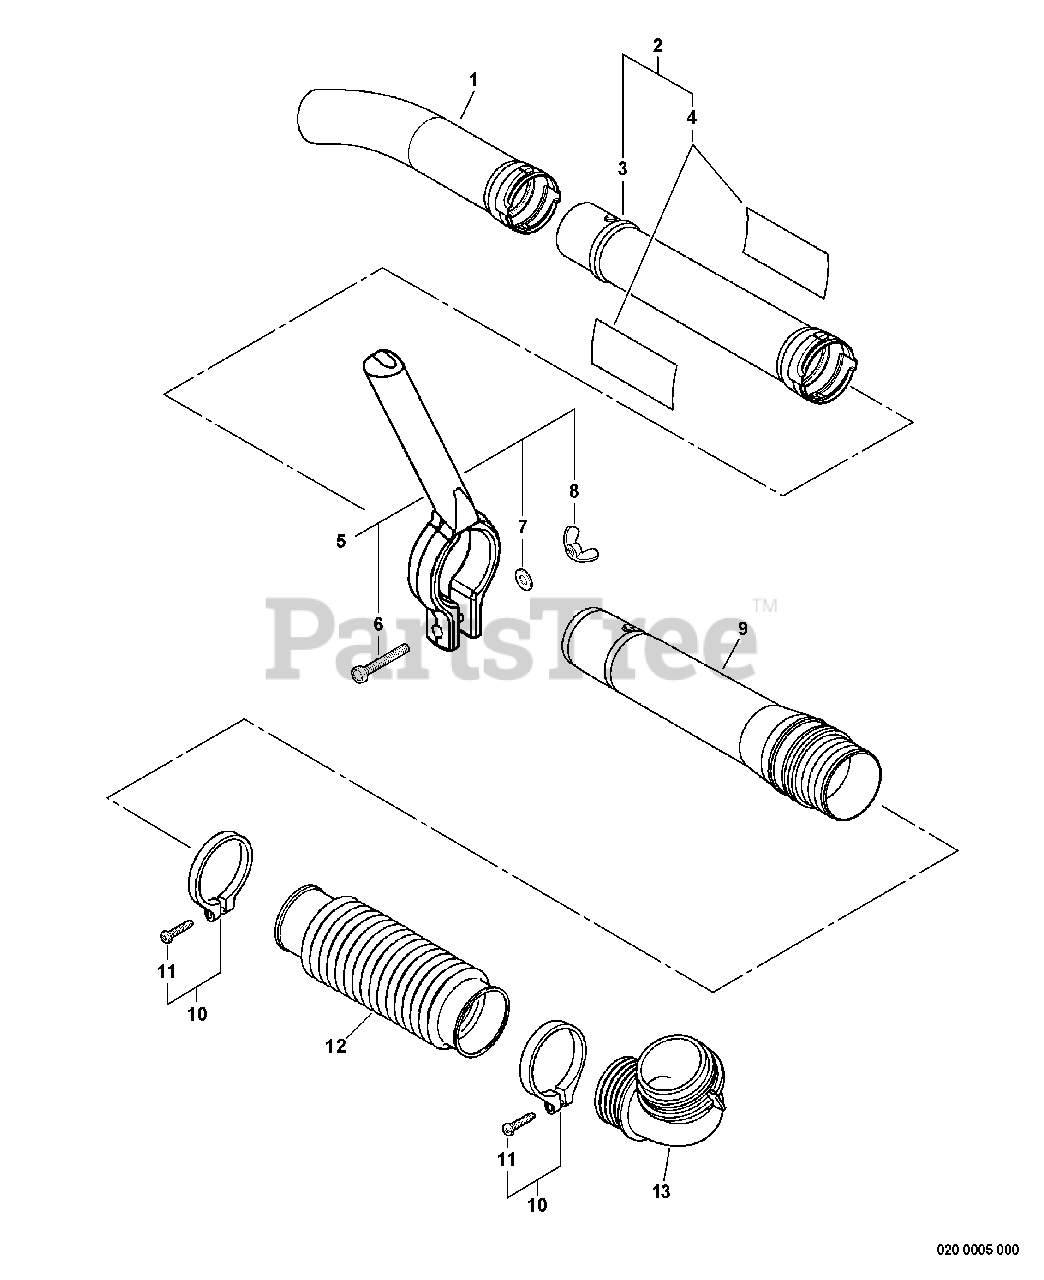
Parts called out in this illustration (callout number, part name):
1	TUBE, BLOWER - CURVED
2	BLOWER TUBE KIT - STRAIGHT
3	TUBE, BLOWER - STRAIGHT
4	LABEL - ECHO
5	HANDLE ASSY
6	BOLT 6×45
7	WASHER 6.5×11.5×0.8
8	NUT, WING 6
9	TUBE, SWIVEL
10	CLAMP 58.7 MM / 82.5 MM
11	SCREW 5×25
12	TUBE, FLEXIBLE
13	TUBE, BLOWER - ELBOW
